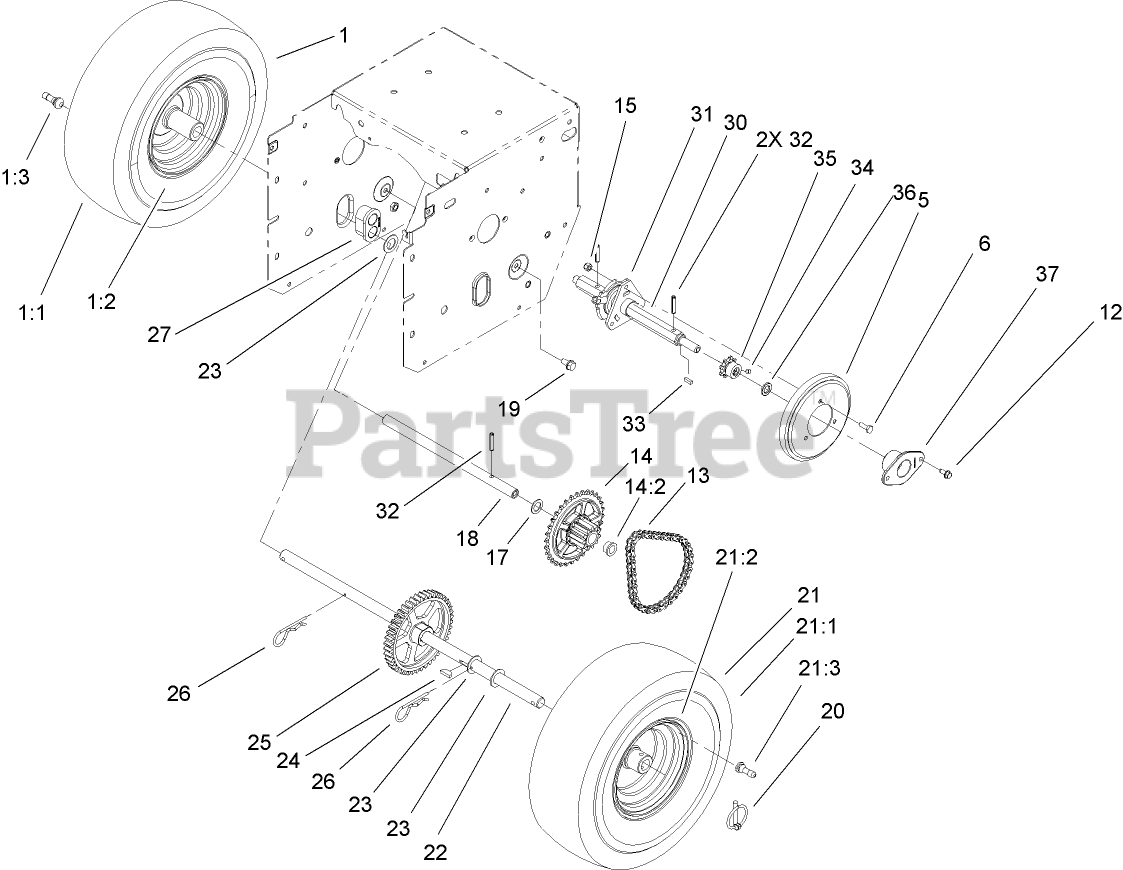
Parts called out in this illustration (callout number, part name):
1	Loose Parts Package
1:2	RIM-TIRE
6	SCREW-HH
12	SCREW-HWH
13	CHAIN-ROLLER
13	LINK-CONNECTING
14	SPROCKET ASM
14:2	BUSHING-FLANGE
15	NUT-LOCK, NI
17	WASHER-FLAT
18	SHAFT-INTERMEDIATE
19	SCREW-HWHTF
20	KLIK PIN ASM
21	Loose Parts Package
21:2	RIM-TIRE
22	SHAFT-AXLE
23	WASHER-THRUST
24	KEY-WOODRUFF
25	GEAR-AXLE, 44 TOOTH
26	PIN-HAIR
27	BEARING-AXLE
30	SHAFT-HEX
31	TRUNNION-HEX
32	PIN-ROLL, SLOTTED
33	KEY-SQUARE
34	SCREW-HSH
35	SPROCKET-8 TOOTH
36	SPACER-BUSHING
37	RETAINER-BEARING
